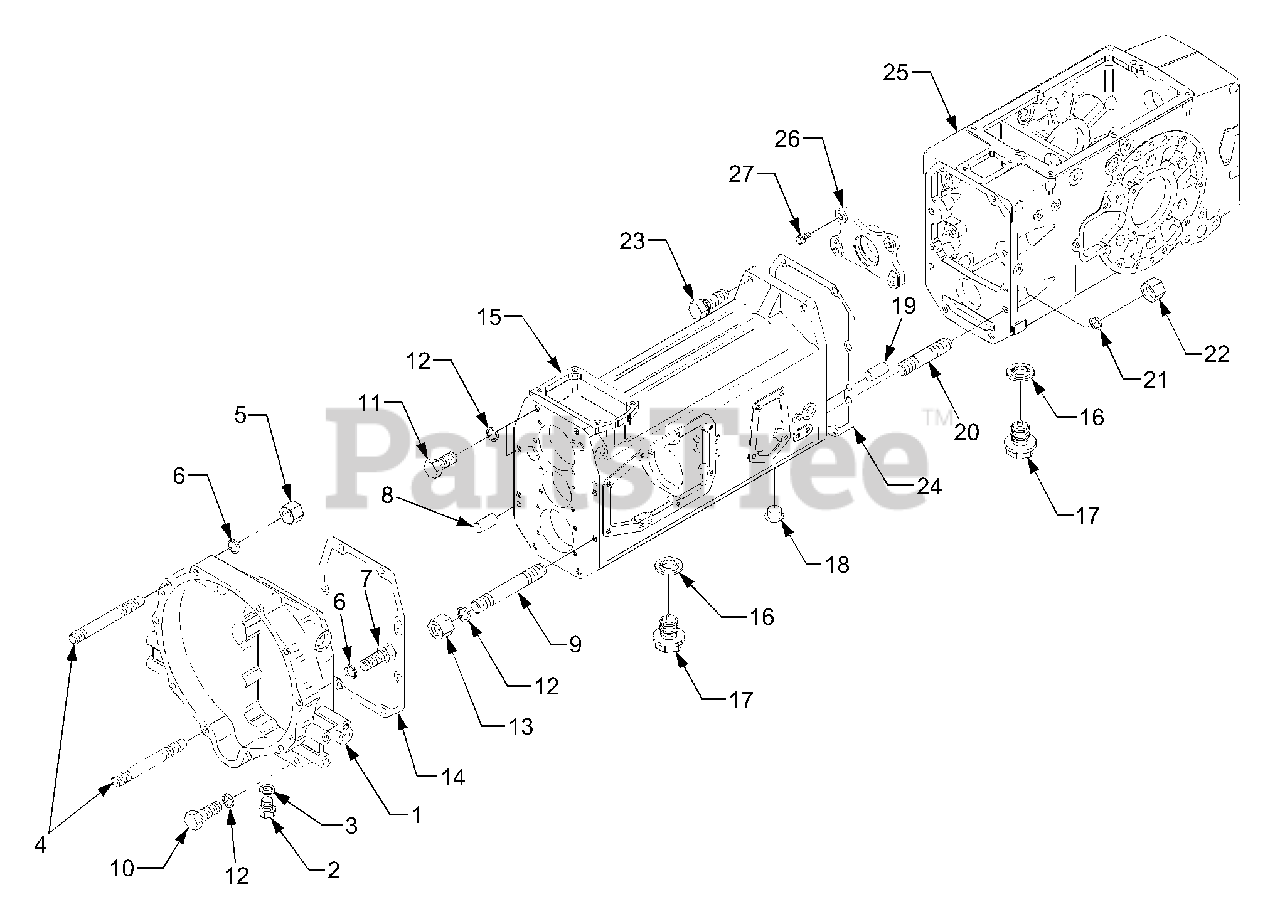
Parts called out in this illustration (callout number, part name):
1	Housing, Clutch
6	Washer, Spring
8	Pin, Straight
12	Washer, Spring
17	Plug, Drain
19	Pin, Straight
21	Washer, Spring
25	Case, Transmission
